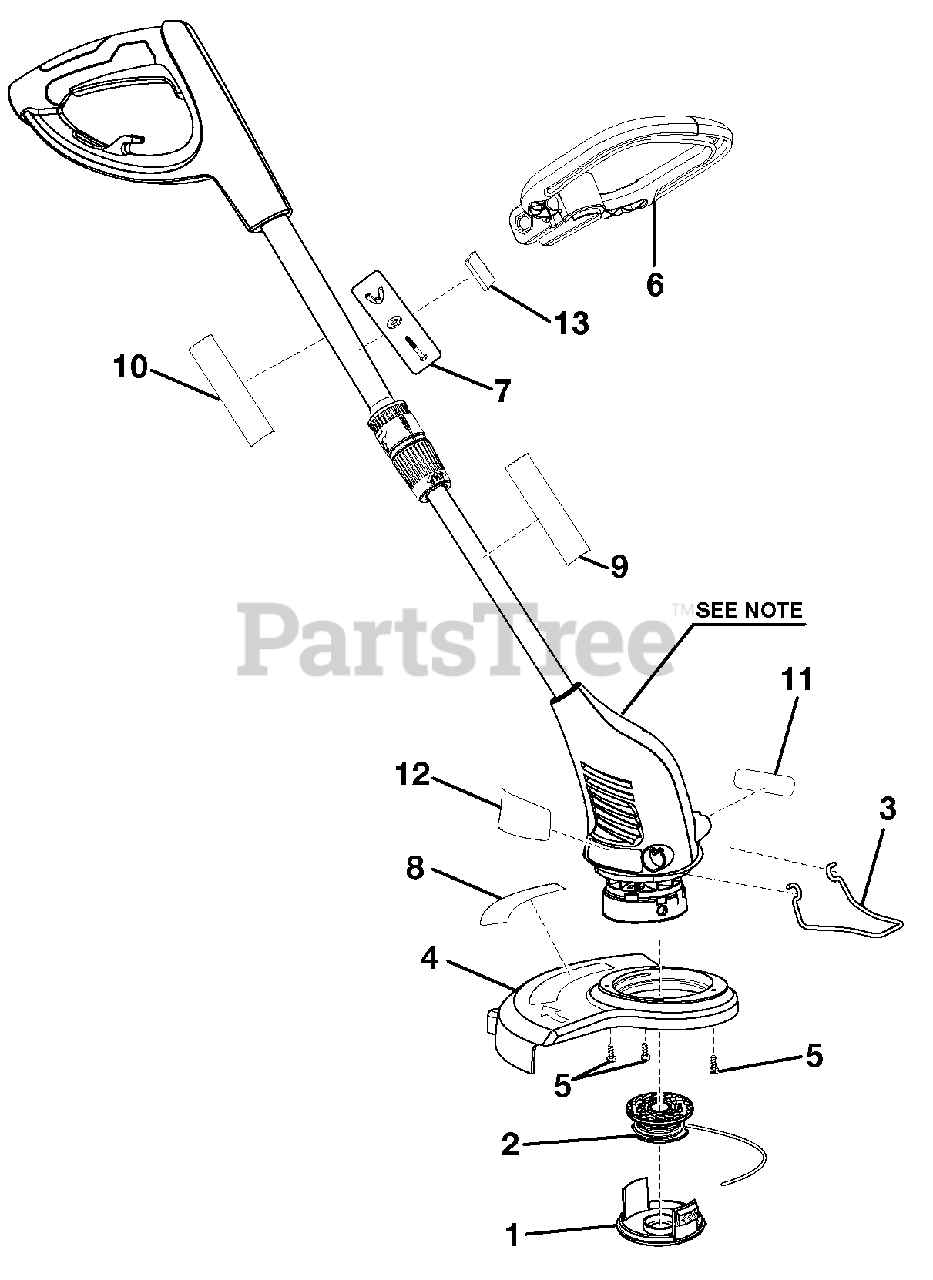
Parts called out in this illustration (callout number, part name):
1	Spool Cap
2	Spool w/Line
3	Edger Guide
4	Grass Shield
5	Screw (M4.2 x 15 mm)
6	Front Handle
7	Fastener Kit
8	Guard Label
9	Data Label
10	Warning Icon Label
11	Logo Label (Motor Housing, Right)
12	Logo Label (Motor Housing, Left)
13	Rubber Bumper
